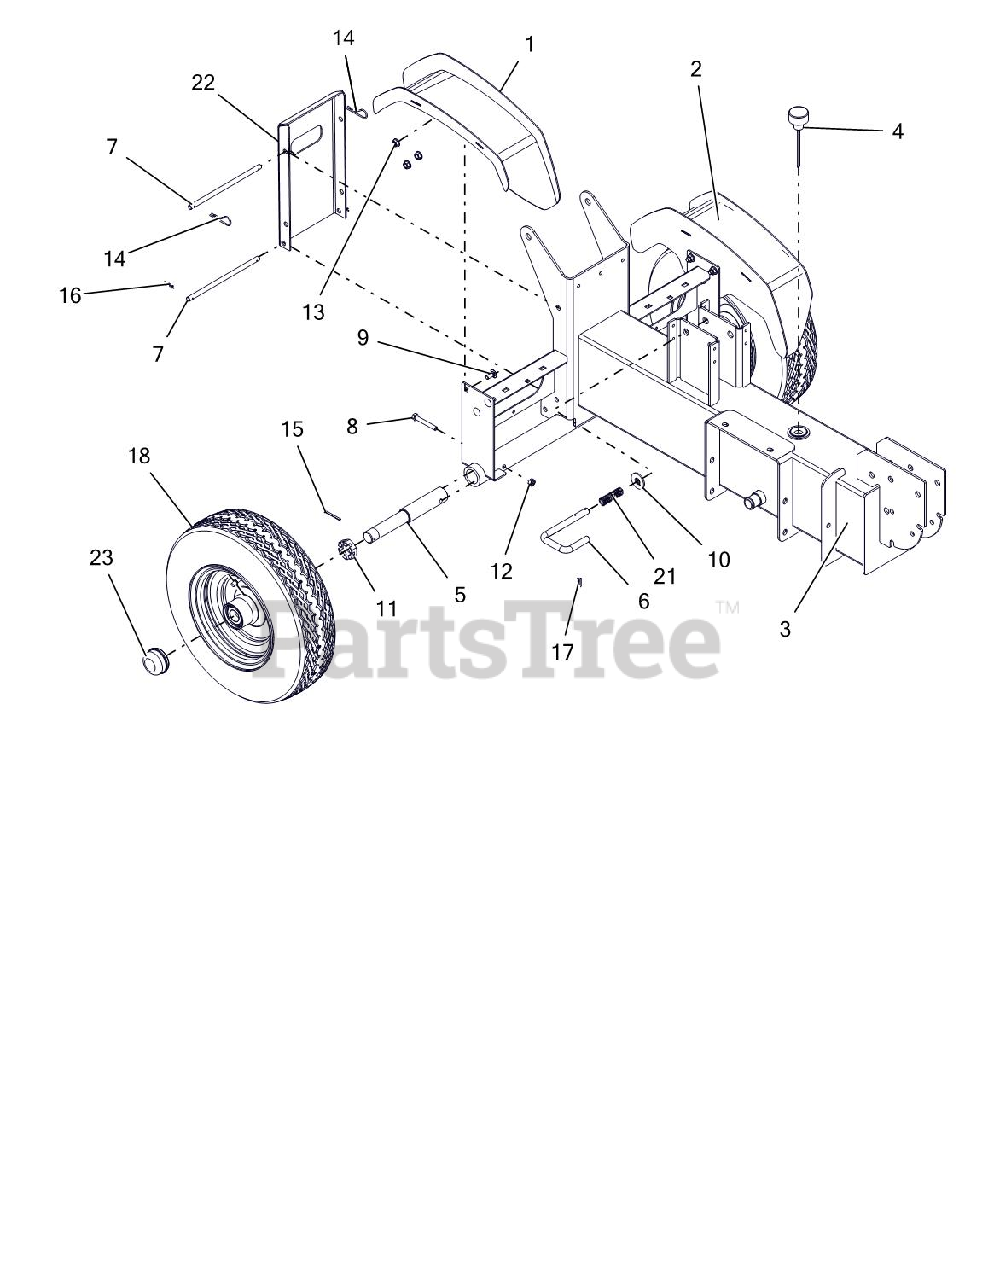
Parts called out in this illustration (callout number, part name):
1	WMT-FENDER-RH
2	WMT-FENDER-LH
3	CHASSIS-SPLITTER W/SFTY DECALS
4	BREATHER, DIPSTICK
5	AXLE, SPLITTER
6	LOCK, BEAM
7	PIN, .373 X 7.30 X 2X.109 THRU
8	@BLT-HEX .31-18X2.25 GR5 YWZC
9	@BLT-RDHDSQNK .31-18X.75 G5YZ
10	@WSHR-FL-STL.563X1.38X.109YWZC
11	NUT-SL 1.0-14
12	@NUT-LK-CTR .31-18 YWZC
13	@NUT-LK-TOP-FLG .31-18 YWZC
14	HAIRPIN, #7 CLIP .094X2.31 YWZ
15	@PIN-CTR .15X1.50 YWZC
16	PIN-HAIR, ENDRIES #25 YWZC
17	CLIP, SPRING
18	ASM,TIRE/WHEEL 4.8/4-8 P47GRAY
21	SPRG, COMP .058X.65X2.13 WLD15
22	REAR STAND W/DECALS (ARIENS)
23	CAP, DUST
